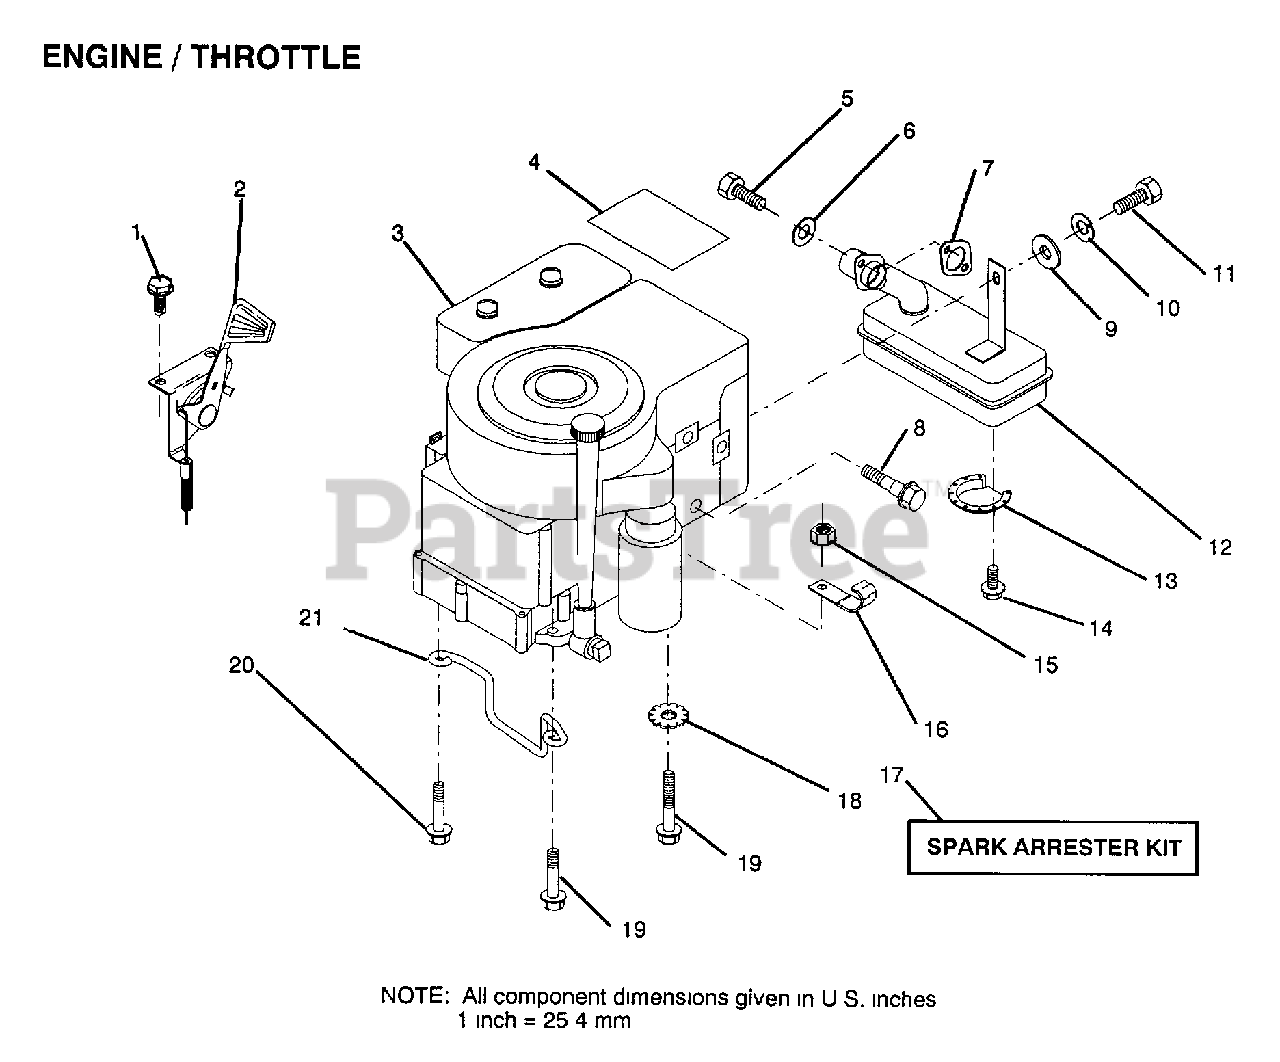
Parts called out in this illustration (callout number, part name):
1	SCREW
3	ENGINE BRIGGS AND STRATTON
4	DECAL.ENG.271967
5	SCREW
6	LOCKWASHER
8	BOLT T
10	LOCKWASHER
12	MUFFLER
13	DEFLECTOR.222573
15	NUT
16	CLIP T
18	LOCKWASHER
19	SCREW LT
20	SCREW LT
21	"KEEPER,DR BELT GR"
